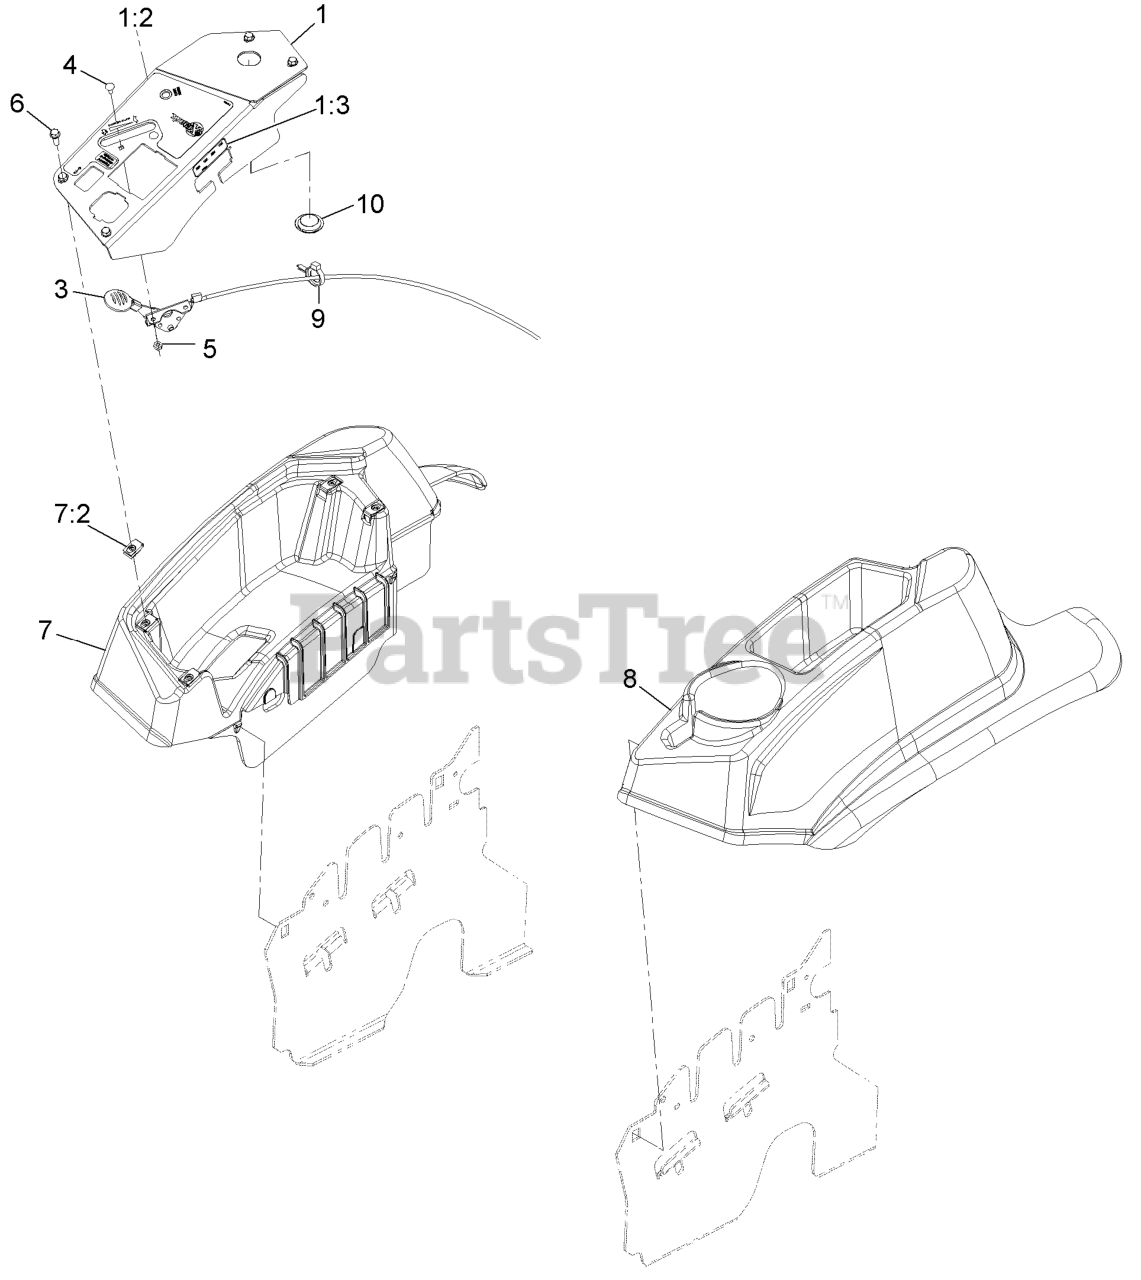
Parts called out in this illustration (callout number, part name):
1	ASM,CONTROL PANEL W/DECAL
1:2	DECAL,CONTROL PANEL EFI
1:3	DECAL-FUSE
3	ASM,THROTTLE CABLE
4	BOLT-CARR
5	NUT-LOCK, NI
6	SCREW-HWH
7	CONSOLE,RH AS ASM
7:2	Nut-Retainer-Panel 1/4-20
8	CONSOLE, LH AS
9	CLAMP-HOSE
10	PLUG-PLASTIC
